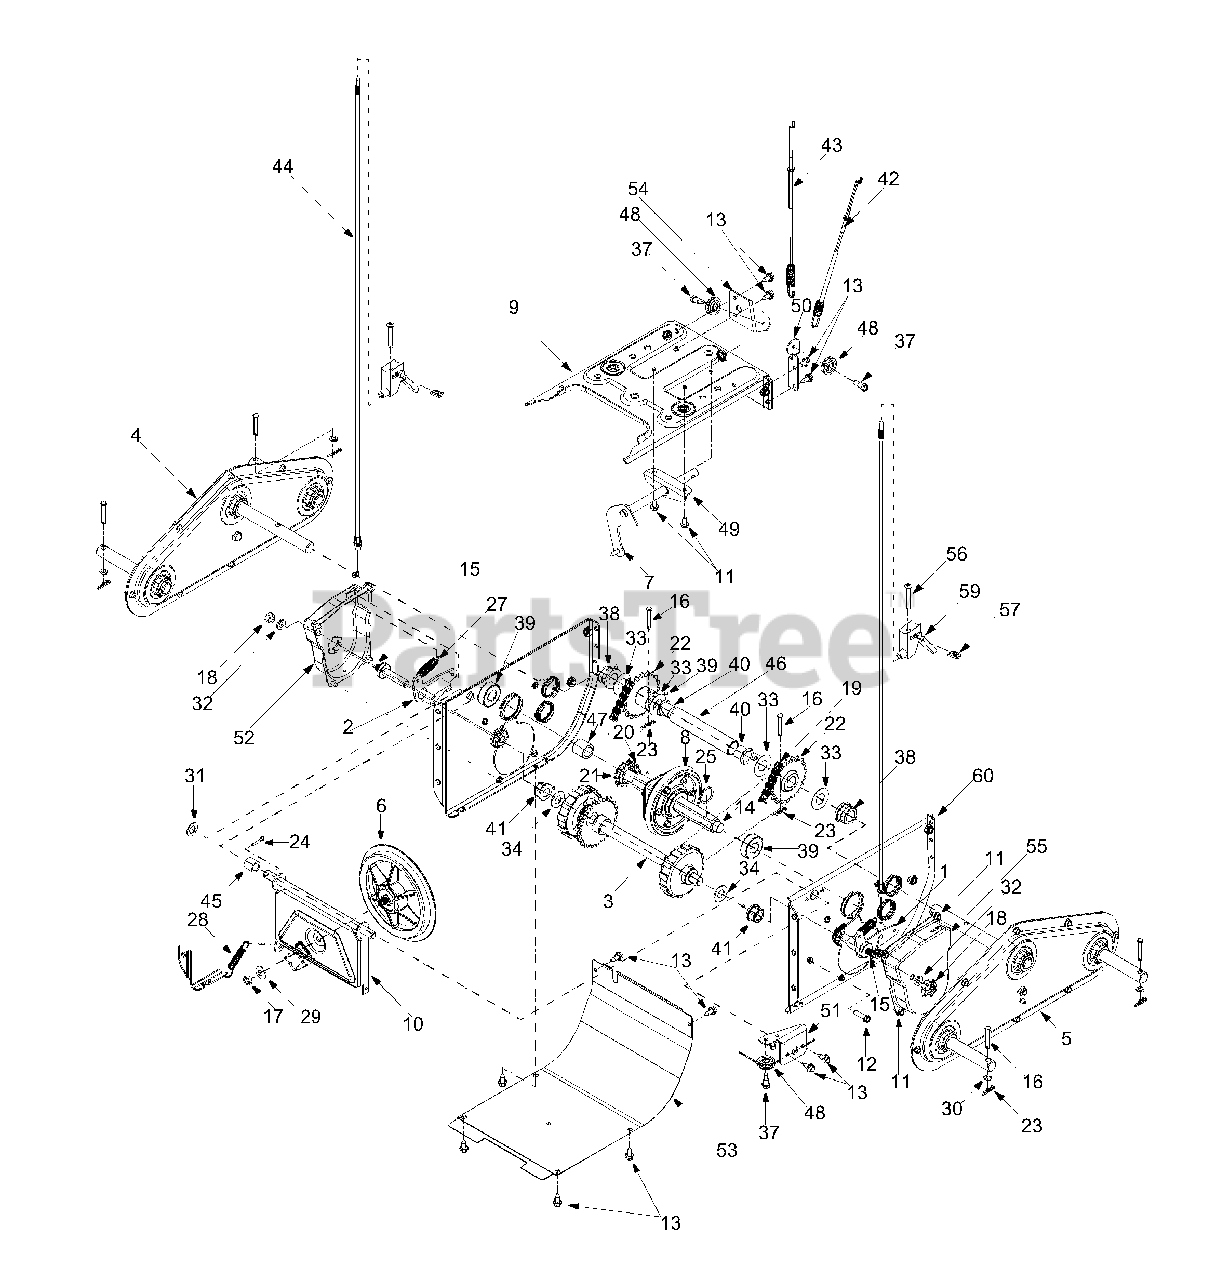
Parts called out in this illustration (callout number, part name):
1	Dogg Assembly: RH
2	Dogg Assembly: LH
3	Shift Assembly: Steerable Drive
4	Chain Case Assembly: RH
5	Chain Case Assembly: LH
6	Friction Wheel Disc Assy.
7	Shift Rod Assembly
8	Wheel Assembly, Friction
11	Hex Washer Screw 1/4-20 x 0.5"
12	Hex Washer Screw 1/4-20 x 1.0"
13	Hex Washer Screw 1/4-20 x .625"
14	Drive Shaft
15	Actuator Shaft
17	Jam Nut 3/8-24 Gr.8
18	Hex Nut: 3/8-16
19	Chain
20	Chain
21	Sprocket: 19T
22	Sprocket
23	Cotter Pin
24	Cotter Pin
25	Snap Ring
27	Extension Spring
28	Extension Spring
29	Bell Washer
30	Flat Washer
31	Flat Washer
32	Lock Washer
33	Flat Washer
34	Flat Washer
37	Shoulder Screw
38	Hex Flange Bearing
39	Ball Bearing
40	Flange Bushing
41	Hex Flange Bearing
42	Auger Clutch Cable
43	Drive Clutch Cable
44	Steering Cable
45	Spacer
46	Support Tube: Axle
47	Spacer
48	Roller Cable
50	Auger Clutch Cable Guide Bracket
51	Front Support Guide Bracket
52	Retaining Shaft RH: Actuator Drive
55	Retaining Shaft LH: Actuator Drive
56	Oval C-Sunk Machine Screw
57	Weld Nut
58	Cable Tie
59	Turn Trigger
59	Label: Eng 9.5HP
